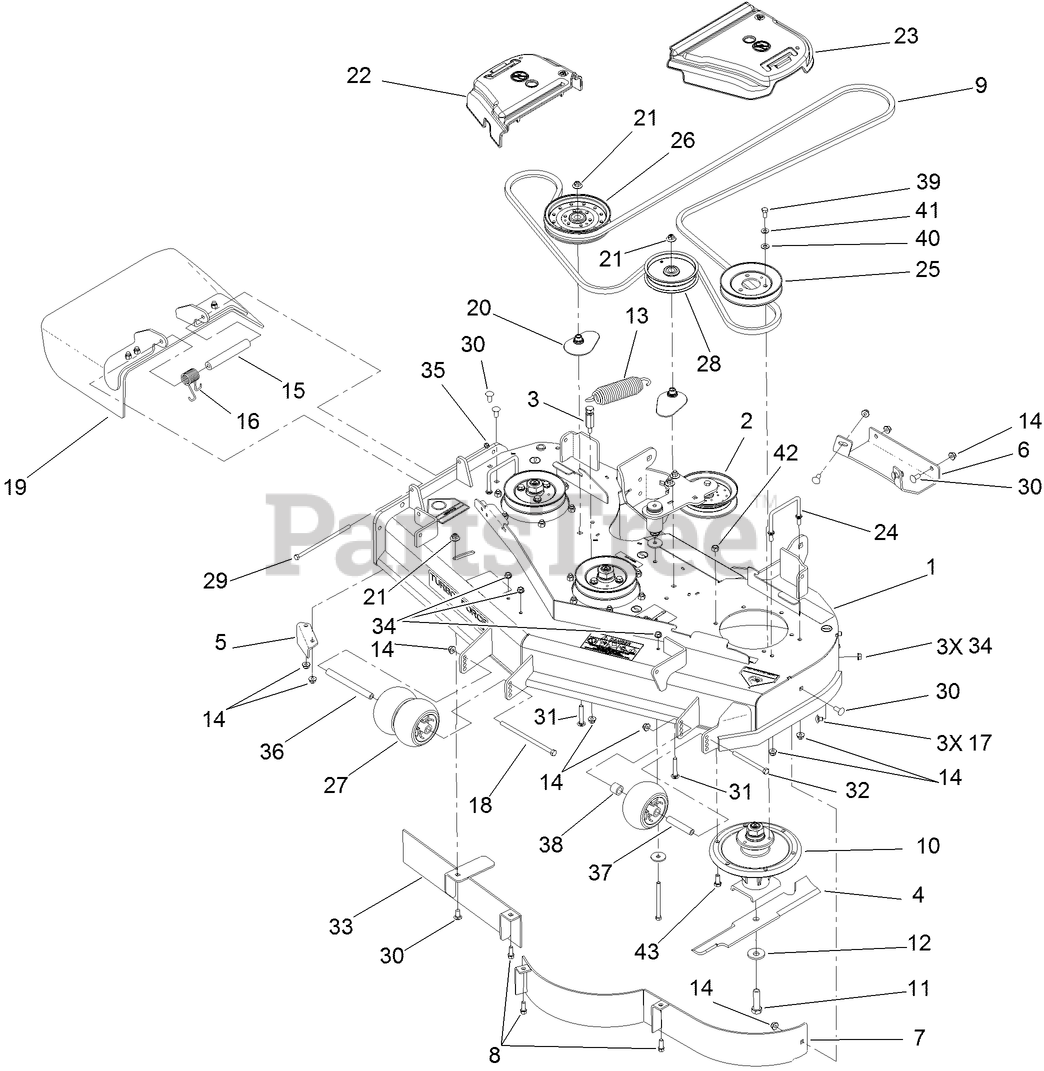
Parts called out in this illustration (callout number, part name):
1	DECK DECAL ASM
2	IDLER ARM ASM
3	ANCHOR-SPRING, TALL
4	BLADE-16.5 INCH (HIGH FLOW)
5	BAFFLE-DISCHARGE
6	PLATE-SKID
8	SCREW-HWH
9	BELT-V
10	SPINDLE ASM
11	SCREW-BLADE
12	Washer-Blade Bolt, Heavy
13	EXTENSION-SPRING
14	NUT-HF, NI
15	SPACER
16	SPRING-TORSION
17	SCREW-CARR
18	SCREW-HH
19	RUBBER DEFLECTOR ASM
20	SPACER-PULLEY
21	NUT-FLANGE, NI
22	COVER-BELT, RH
23	COVER-BELT, LH
24	WIREFORM-COVER
25	PULLEY
26	PULLEY-IDLER, FLAT
27	ROLLER-SCALP, ANTI
28	PULLEY-IDLER
29	SCREW-HH
30	SCREW-CARR
31	BOLT-CARR, SHORT NECK
32	SCREW-HH
33	BAFFLE ASM
34	NUT-HHF, WHIZ
35	NUT-LOCK, NI
36	SPACER-WHEEL
37	TUBE-SPANNER
38	TUBE-SPACER
39	SCREW-HH
40	WASHER-FLAT
41	WASHER-BELLEVILLE
42	NUT-LOCK, NI
43	SCREW-HH
